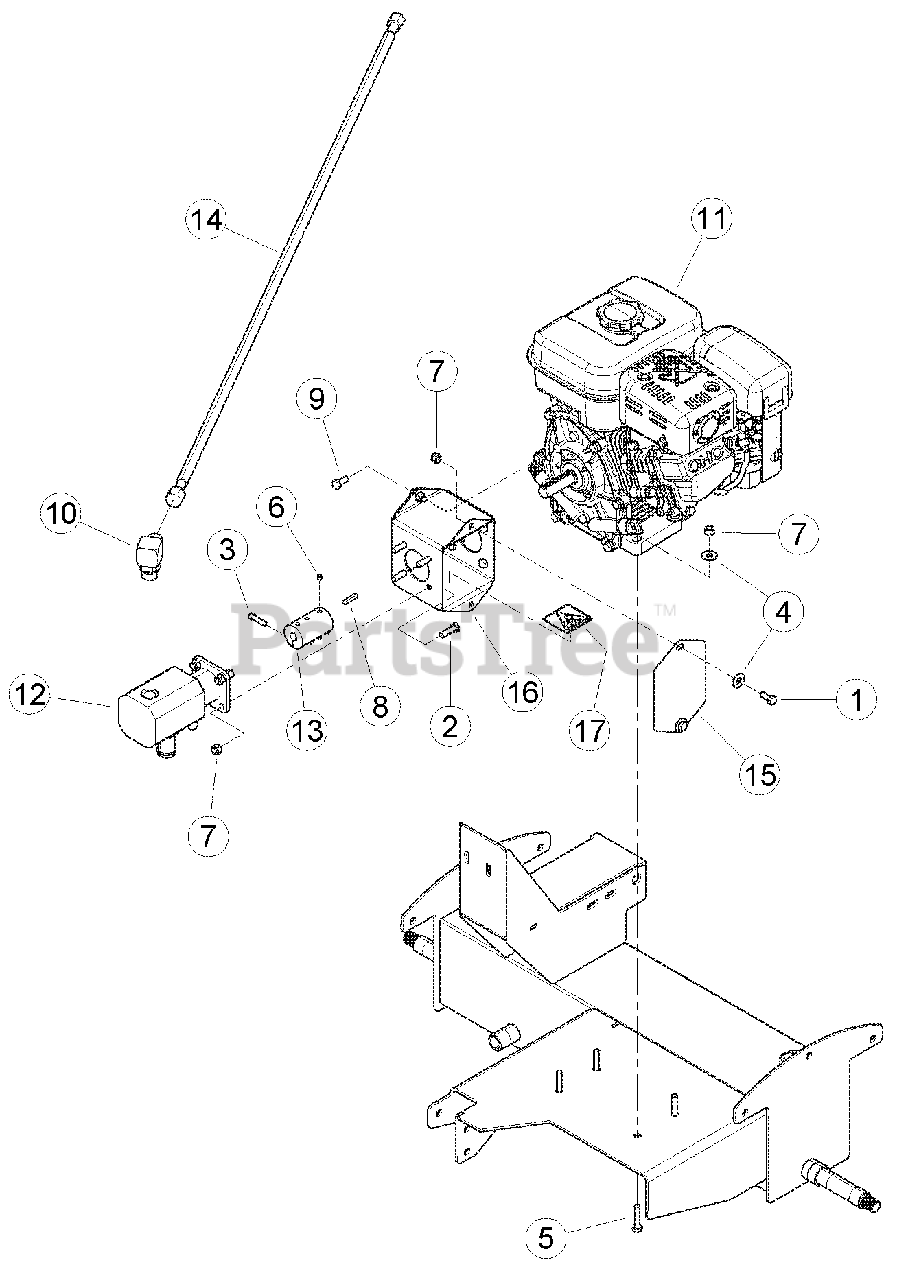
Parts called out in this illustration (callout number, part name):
1	BOLT, 5/16 X 3/4 HEX GR5 ZP
2	BOLT, 5/16 X 1 HEX GR5 NC ZP
3	BOLT, 1/4 X 1 SOC HD CAP SCRW (PN 15242 REMOVED)
5	BOLT, 5/16 X 1-1/2 HEX GR5 ZP
6	SCREW, 1/4-20 X 1/4 KNR CUP SKT SET (PN 15332 REMOVED)
7	NUT, 5/16 NE NYLOCK ZP
8	SQUARE KEY, 3/16 X 1 LONG
9	BOLT, 5/16-24 X 3/4 HEX GR5 NF ZP
10	ADAPTER, -10 MORING / -10 MJIC 90 DEG.
11	ENGINE, SUBARU 170CC SP170 (FOR SERVICE CONSULT ENGINE OWNER'S MANUAL OR YOUR NEAREST AUTHORIZED SUBARU INDUSTRIAL ENGINE DEALER.)
13	COUPLER, SPLIT 3/4" TO 1/2" SHAFT (PN 31963-00 REMOVED)
14	HOSE, .50 X 50 -10 FJICSW / -10 FJICSW
15	PLATE, PUMP MOUNT COVER
16	ASSEMBLY, PUMP MOUNT, SERVICE PART
17	DECAL, SHIELD DANGER ISO
